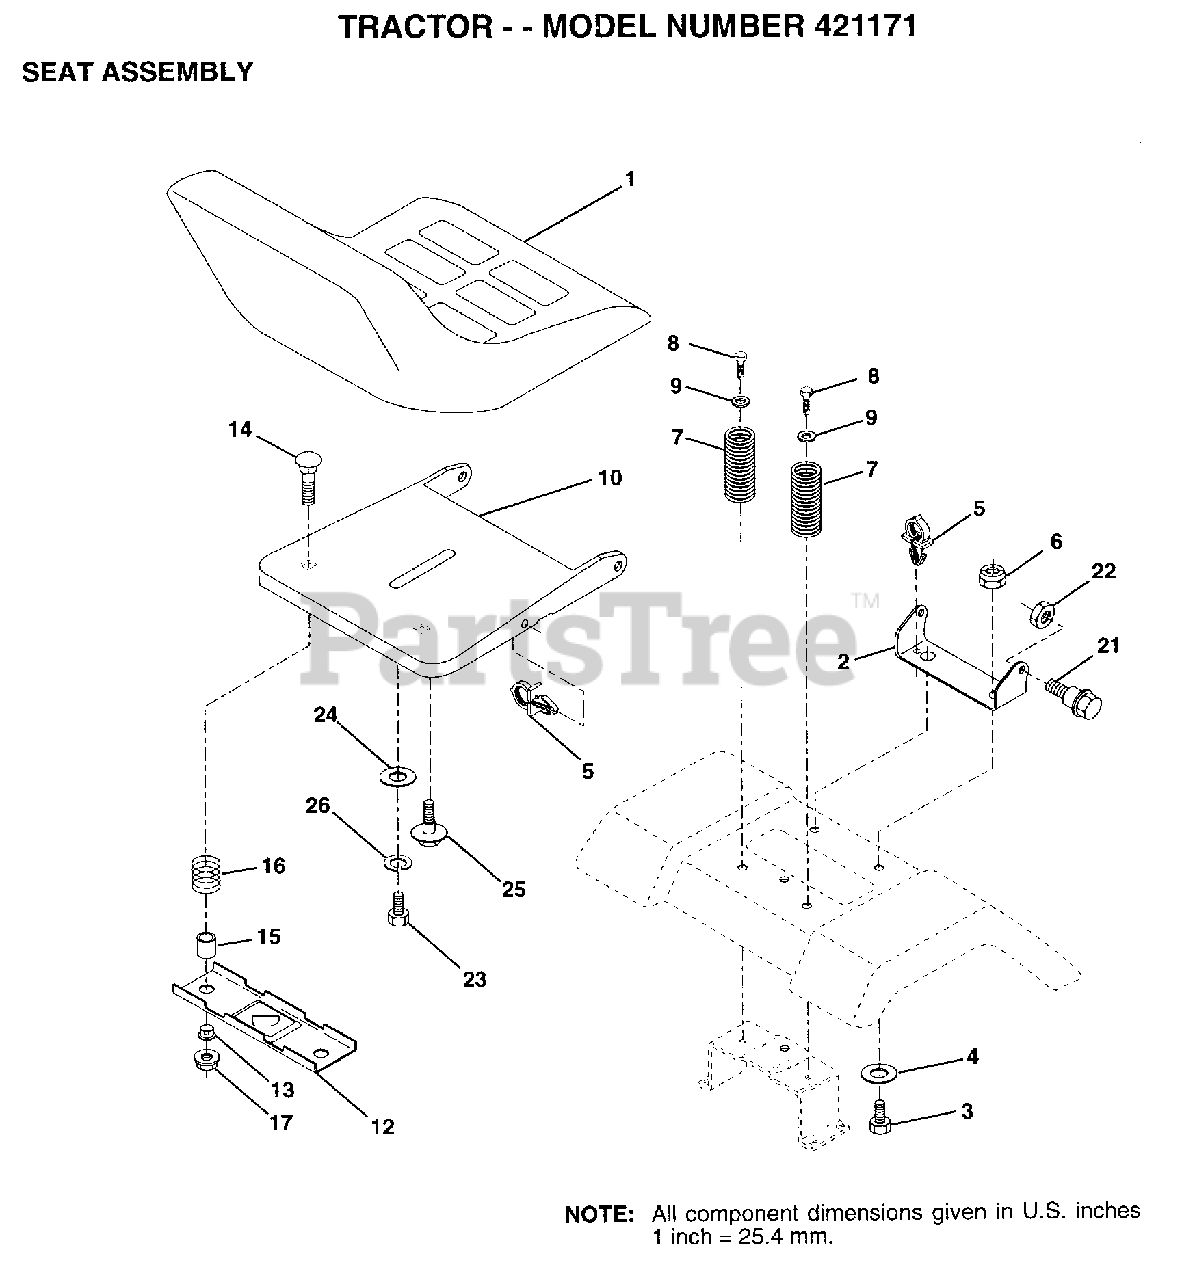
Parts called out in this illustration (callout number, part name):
1	SEAT
2	BRACKET PVT SEAT
3	BOLT
4	WASHER PM
5	CLIP.PUSH-IN.HING
6	NUT
7	SPRING COMPRESSIO
8	SCREW GTV
9	WASHER
12	BRKT SWITCH
13	BUSHING
15	SPLIT SPACER
16	SPRING
21	BOLT.SHLD.5/16-18
22	NUT
23	BOLT
24	WASHER
25	"BOLT,SHOULDER"
26	LOCKWASHER
